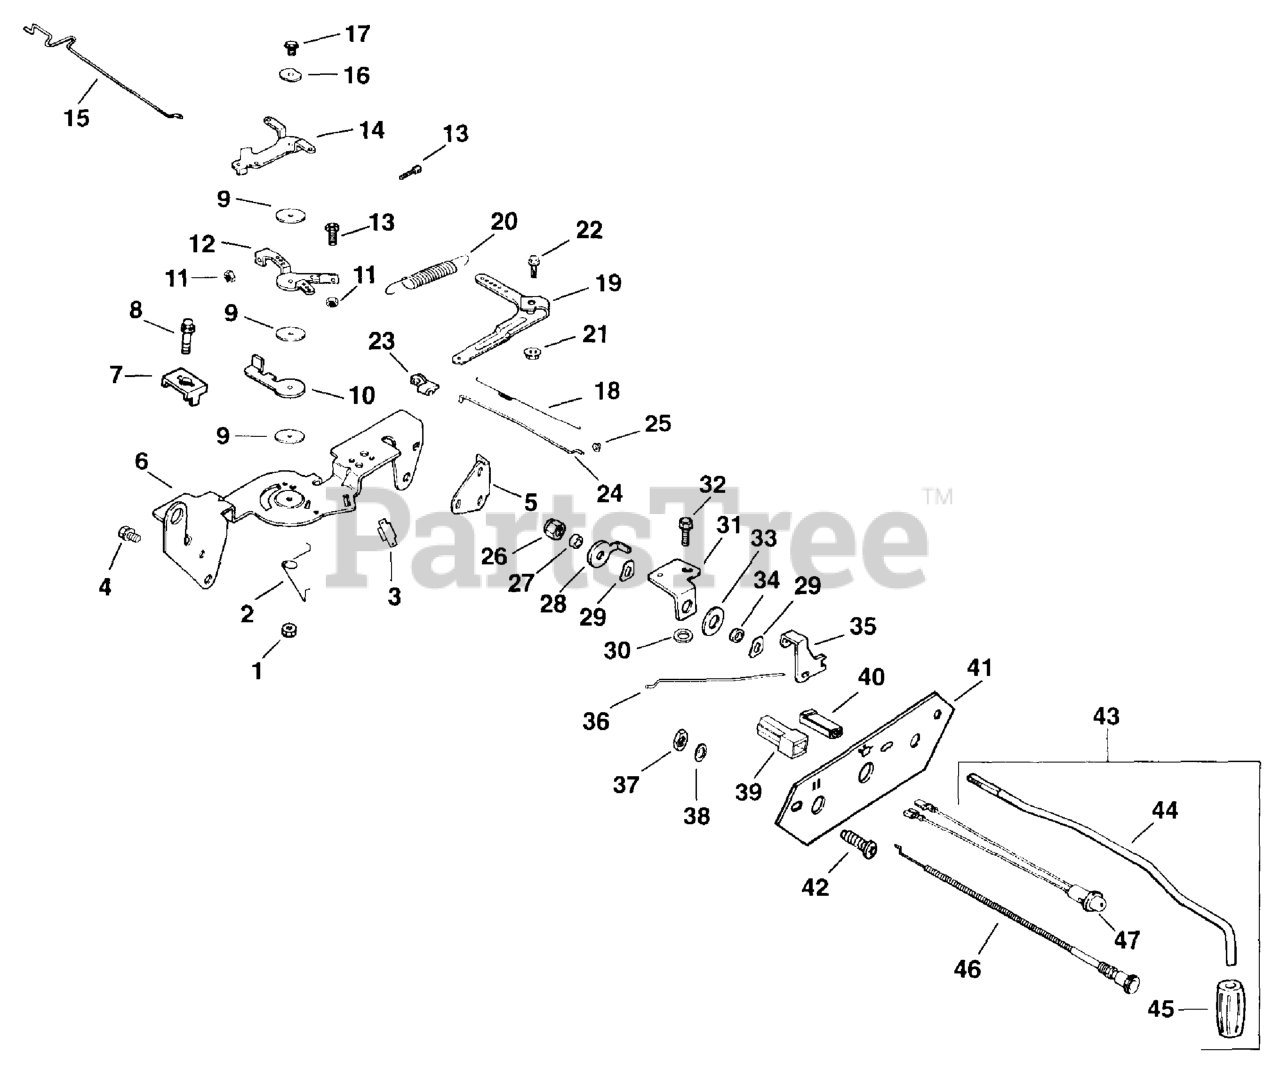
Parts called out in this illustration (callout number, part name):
1	Nut, hex. flange M5x0.8
4	SCREW - USE M-645016
6	BRACKET - USE 24 126 56
7	CLAMP, CABLE
8	Screw, hex. flange M5x0.8x16
9	WASHER, FLAT 5.5 MM
10	LEVER,THROTTLE ACTUATOR-USE(24 090 65-S
11	Nut, hex. flange M4x0.7
12	LEVER, THROTTLE CONTROL
13	Screw, hex. cap M4x0.7x30
14	LEVER, CHOKE
16	WASHER, SPRING 1/4"
17	Screw, hex. flange M5x0.8x20
18	SPRING, LINKAGE
19	LEVER, GOVERNOR - DISCONTINUED
20	SPRING, GOVERNOR (CLEAR)
21	NUT - USE M-641060
22	Screw, hex. cap M6x1.0x25
23	BUSHING, THROTTLE LINKAGE
24	LINKAGE, THROTTLE
25	BUSHING, LINKAGE RETAINING
26	Nut, hex. M6x1.0
27	BOLT - USE 25 086 47
29	WASHER, SPRING 1/4"
30	WASHER - USE M-631005
31	BRACKET, SPEED CNTRL SHFT
32	SCREW - USE M-545010
35	LEVER - USE 24 090 22
36	LINKAGE, SPEED CONTROL
37	NUT, 3/8-24 GRADE 2 USE 25 100 25-S
38	WASHER, FLAT 1/4" (O.D. 1/2")
41	PANEL, FRONT CONTROL
42	SCREW, PHL HD 11-16X3/4"
43	KIT, SPEED CONTROL SHAFT
44	SHAFT, SPEED CONTROL
45	KNOB, SPEED CONTROL
46	CABLE ASSEMBLY, CHOKE
